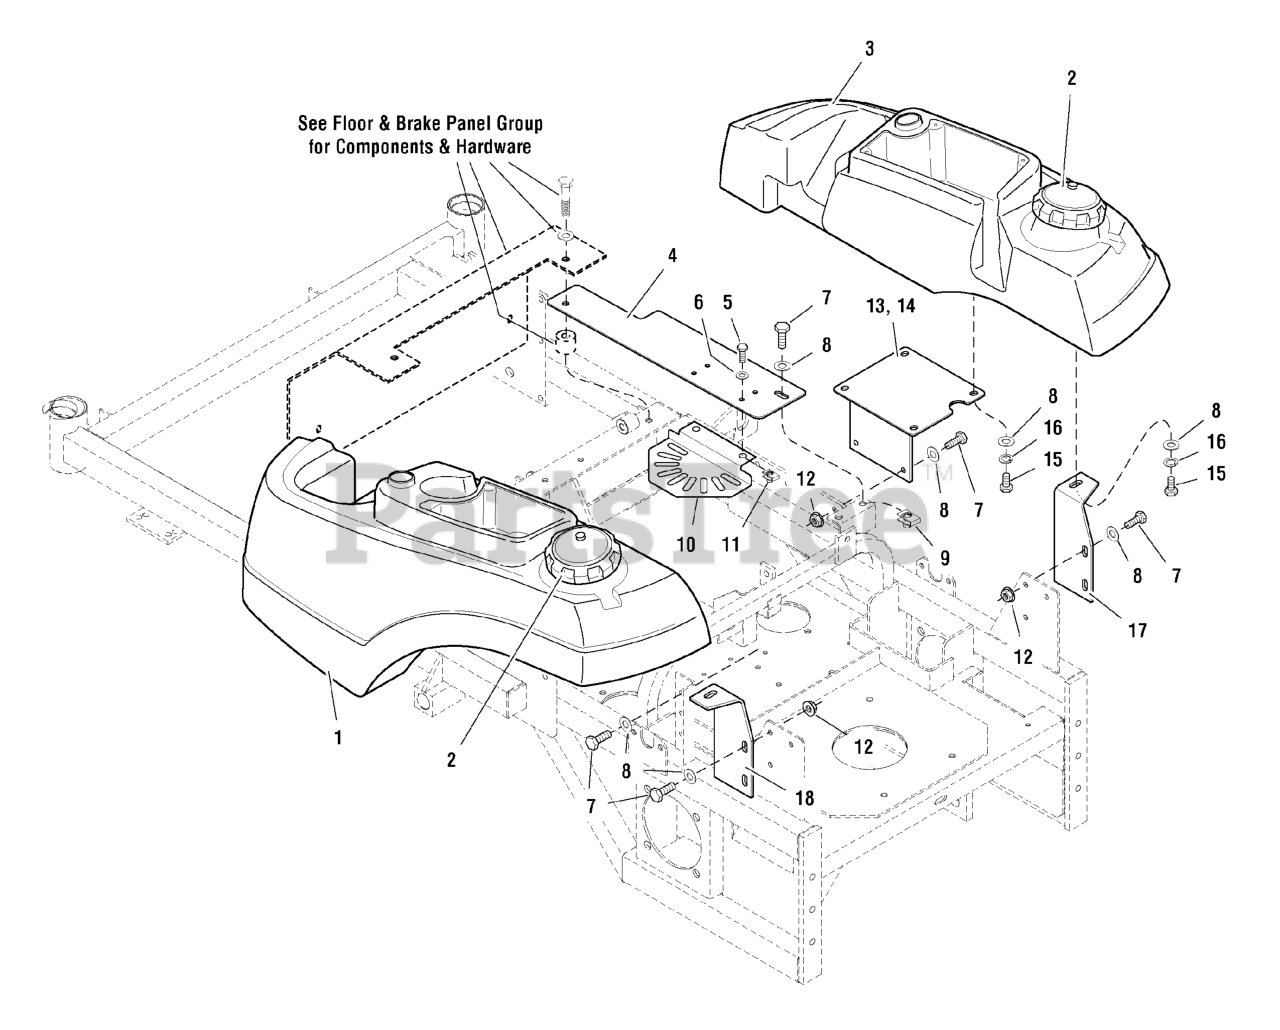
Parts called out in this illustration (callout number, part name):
1	FUEL TANK, IS1000Z, LH
1	Filler Neck
2	CAP, GASOLINE, VENTED
3	FUEL TANK, IS1000Z, RH
4	COVER, Fan Shield Mount
5	BOLT, 1/4-20 x 3/4
6	WASHER, 1/4 SAE
7	BOLT, 5/16-18 X 1 GD5 YZ
8	WASHER, 5/16" SAE
9	BODY CLIP, 5/16-18-7GA MATERIAL
10	FAN SHIELD
11	BODY CLIP, 1/4-20
12	NUT, 5/16-18 HEX SERRATED FLANGE (SMALL)
13	FUEL TANK MOUNT-RH
14	FUEL TANK MOUNT-LH
15	BOLT, 5/16-18 X 3/4 GD5
16	WASHER, 5/16 LOCK CZ
17	BRACKET, Fuel Tank Support-RH
18	BRACKET, Fuel Tank Support-LH
